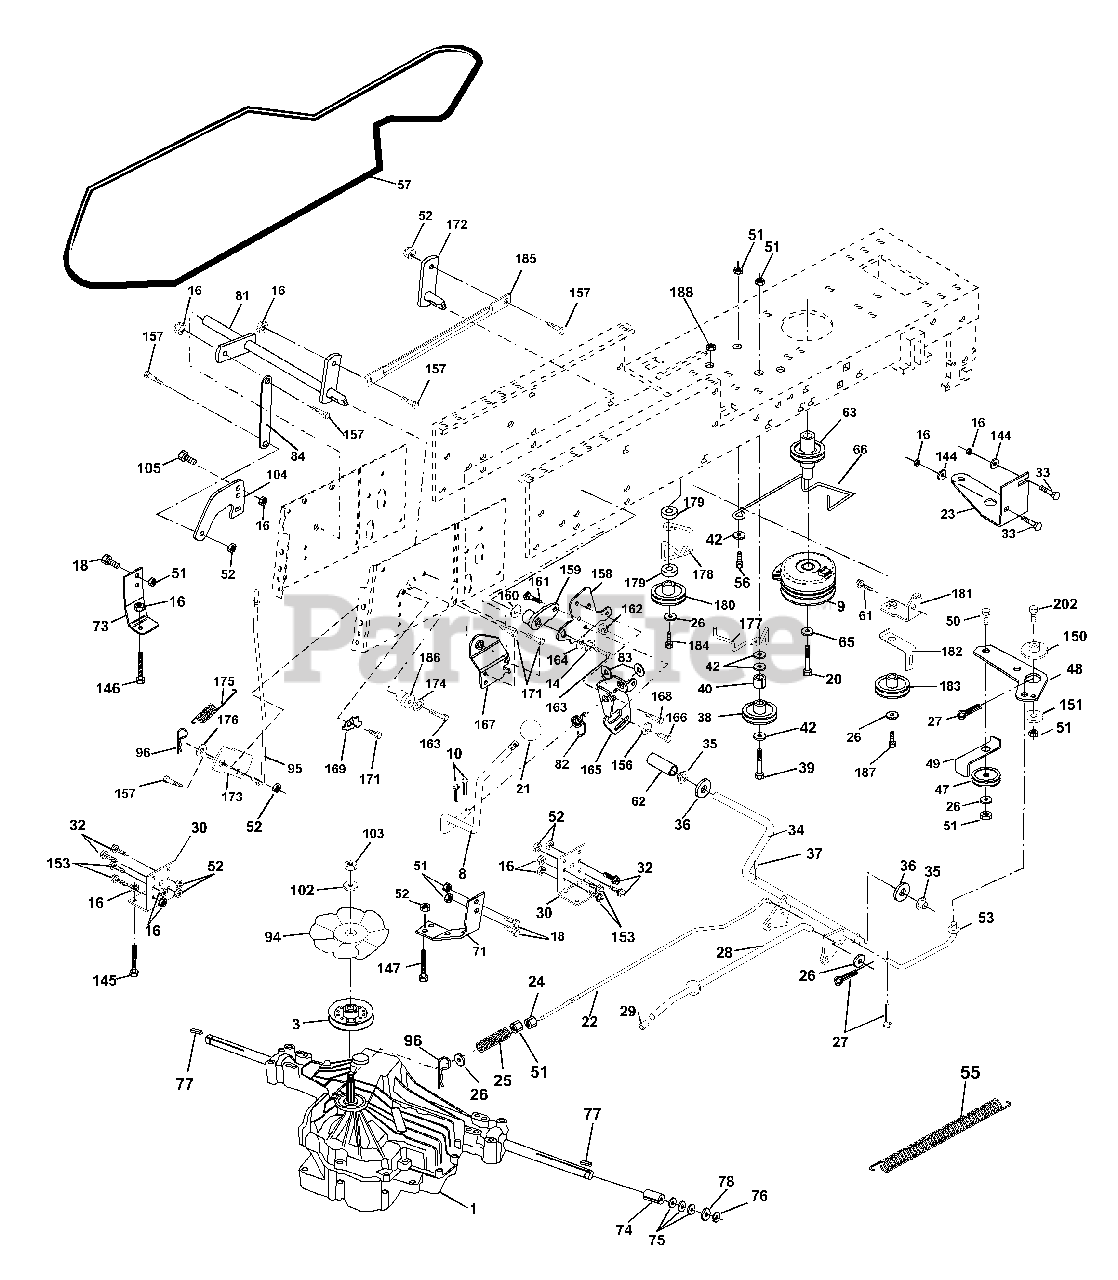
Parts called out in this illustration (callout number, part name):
1	Transaxle Hydro Gear Model 331-0650 (See Breakdown)
3	Pulley, Transaxle
8	Rod Shift Fender Adjust Evx 80 lb
9	Clutch Elect
10	Pin Cotter 1/8 x 1 CAD
14	Washer Lock Hvy Helical
18	Bolt Fin Hex 3/8-16 Unc x 1 Gr. 5
20	Bolt, Hex 7/16-20 x 4-1/4
21	Knob, Duckhead 1/2-13
22	Rod, Brake Hydro
23	Bracket Asm Clutch
24	Nut Hex Jam 3/8-16
25	Spring, Brake Rod
26	Washer 13/32 x 13/16 x 16 Ga.
27	Pin Cotter 1/8 x 3/4 CAD.
28	Rod, Parking Brake
29	Cap, Parking Brake
30	Bracket, Transaxle
33	Bolt Rdhd Sqnk 5/16-18 unc x 3/4
34	Shaft, Foot Pedal
35	Bearing, Nylon
36	Washer 21/32 x 1 x 16 Ga
37	Pin, Roll
38	Pulley, Flat
39	Nut Rdhd 3/8-16 Unc x 2-3/4 Gr. 5
40	Spacer, Split
42	Washer 13/32 x 13/16 x 12 Gauge
47	Pulley, Idler, V-Groove
48	Bellcrank Assembly
49	Retainer, Belt
50	Bolt Carr Sh 3/8-16 x 1-1/2 Gr. 5
51	Nut Crownlock 3/8-16 UNC
52	Nut Crownlock 5/16-18 UNC
53	Link, Clutch
55	Spring, Return, Clutch
56	Bolt Fin Hex 3/8-16 UNC x 1-1/4
57	V-Belt, Ground Drive
61	Screw 3/8-16 x 3/4
62	Cover, Pedal
63	Pulley, Engine
65	Washer
66	Keeper Belt Engine
71	Strap Torque Lh Hydro
73	Strap Torque Rh Hydro
74	Spacer, Split
75	Washer 25/32 x 1-1/4 x 16 Gauge
77	Key, Square
78	Washer 25/32 x 1-5/8 x 16 Gauge
81	Shaft Asm. Cross
82	Spring Torsion
83	Washer 17/32 x 3/4 x 16 Ga.
84	Link Transaxle
94	Fan, Hydro 7"
95	Rod Bypass CRD
96	Retainer Spring 1" Zinc/Cad
102	Washer Beliville .501D x 1.50D
103	Nut, Hex, Jam Toplock 1/2-20 UNF
104	Arm, Control Hydro
105	Screw Cap Hex 5/16 x 18 x 1
144	Washer 11/32 x 5/8 x 16 Ga.
145	Bolt Hex Flghd 5/16-18 Gr.5
146	Bolt Hex Flghd 5/16-18 x 2-1/4
147	Bolt Hex Flghd 5/16-18 x 1-1/2
150	Bushing Bellcrank
151	Washer 13/32 x 2 x 10 Ga.
153	Bolt Hex Hd 5/16-18 UNC x 1
156	Washer Srrted 5/16 ID x 1.125
157	Bolt Shoulder 5/16-18 Unc - 2A
158	Bracket Shift Mount
159	Hub Tapered Flange Shift Lt
160	Washer 29/32 x 1-1/4 x 16 Ga
161	Bolt Rdhd Sqnk 1/4-20 x 3/4 Gr. 5
162	Nut Crownlock 1/4-20 Unc
163	Bolt Hex Fin 1/4-20 Unc x 1 Gr 5
164	Washer 5/8 x .281 x 10 Ga
165	Bracket Pivot Lever
166	Screw 5/16-18 x 5/8
167	Bracket Support Shift CRD
168	Bolt Shoulder 5/16-18 x .561
169	Plate Fastening Cross Shf. Stlt/CRD
172	Shaft Asm Shifter Frt CRD
173	Bracket Hydro Bypass CRD
174	Washer Lock 1/4
175	Spring Bypass CRD
176	Washer 7/32 x 1/2 x 16 Ga
177	Keeper Flat Idler
178	Keeper Belt Idler
179	Washer Sintered
180	Pulley Flat Idler
181	Bracket Idler Ground Drive CRD
182	Keeper Belt 2.5"OD V-Idler CRD
183	Pulley V-Idler 2.50" OD CRD
184	Scr Hexwsh Thdrol 3/8-16 x 2-3/4
185	Link shift CRD Hydro 0650
186	Hub Tapered Round CRD
188	Bushing Snap Split Blk
190	Screw Thdrol 3/8-16 x 1/2 TYTT
191	Bolt Shoulder 5/16-18 Unc -2A BD
192	Nut Crown Lock 5/16-18 Slvr DC
193	Nut Crown Lock 5/16-18 Slvr DC
194	Nut Crown Lock 3/8-16 Unc
